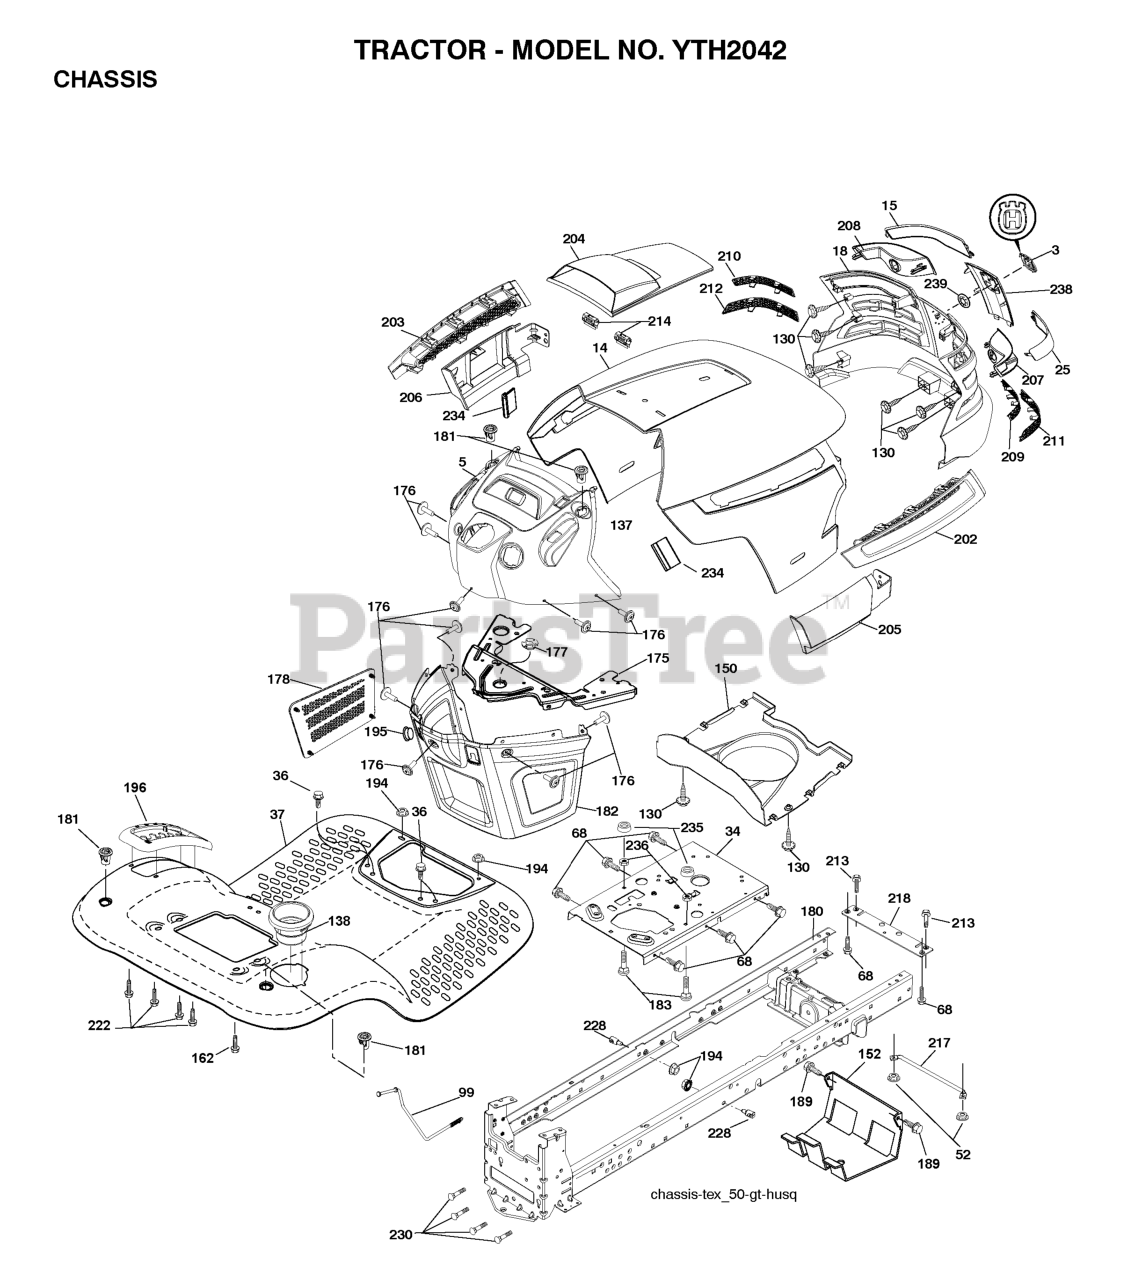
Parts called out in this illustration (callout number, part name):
3	RP LOGO
14	HOOD
15	LENS.LH.TEX.GT.HUSQ.CL
18	GRILL.ASM.HUSQ.TG/CRD.W/TRIM
25	LENS.RH.TEX.GT.HUSQ.CL
34	PLATE.ENGINE.WELDED.CHASSIS
36	SCREW 5/16"
37	FEND/FTRST.PCH.CPH.NFW
52	LOCKNUT
68	Screw 5/16-18 x 1/2 Hex, Self Tapping 5/16-18 x 1/2
99	ROD ASM BYPASS
130	SCREW
138	CUPHOLDER.TL.TEX.418
150	AIR.DUCT.TEXGT.HUSQ.31
152	SHIELD.BROWNING.W/TEX
162	SCREW.HI-LO.CONSOLE
175	PLATE.CROSSMEMBER.HUSQ
176	SCREW.#10-24X5/8.RN.QU
177	BUSHING, STEERING
178	CARGO.ASM.NET.TXGT.W/C
180	CHASSIS
181	BUSHING.MNT.FEND.CRGO.
182	DASH.LOWER.COMMON.12V.
183	BOLT.5/16-18X1-1/4 FULL.THREAD
189	SCREW
194	NUT LOCK HEX FLANGE 5/16-18
195	PLUG.HOLE.DASH.LOWER.12V.BLK
196	CONSOLE.ASM.DECK.LIFT.
202	VENT.SIDE.HOOD.HUSQ.RH.GREY
203	VENT.SIDE.HOOD.HUSQ.LH.GRAY
204	VENT.TOP.HOOD.HUSQVARN
205	SKIRT.HOOD.SIDE.HUSQ.RH.GREY
206	SKIRT.HOOD.SIDE.HUSQ.LH.GREY
207	BEZEL.RH.TEX.GT.HUSQ
208	BEZEL.LH.TEX.GT.HUSQ
209	INSERT.HEX.GRILL.HUSQ.GREY
210	INSERT.HEX.GRILL.HUSQ.
211	INSERT.HEX.GRILL.HUSQ.
212	INSERT.HEX.GRILL.HUSQ.
213	BOLT
214	CLIP.RETAINER.TINNER.
217	ROD PIVOT CHASSIS/HOOD
218	X-PIECE.HOOD.STOP.NON/
222	SCREW.1/4-20X5/8
228	STUD.FASTNER.W/ANTI-ROTATE
230	SHOULDER BOLT 5/16-18TT
234	BUMPER.HOOD.TEX.HUSQVARNA
235	SPACER FENDER
236	NUT.CENTERLOCK.5/16-
238	TRIM.HUSQ.TG/CRD.SERVICE
239	NUT PUSH M
